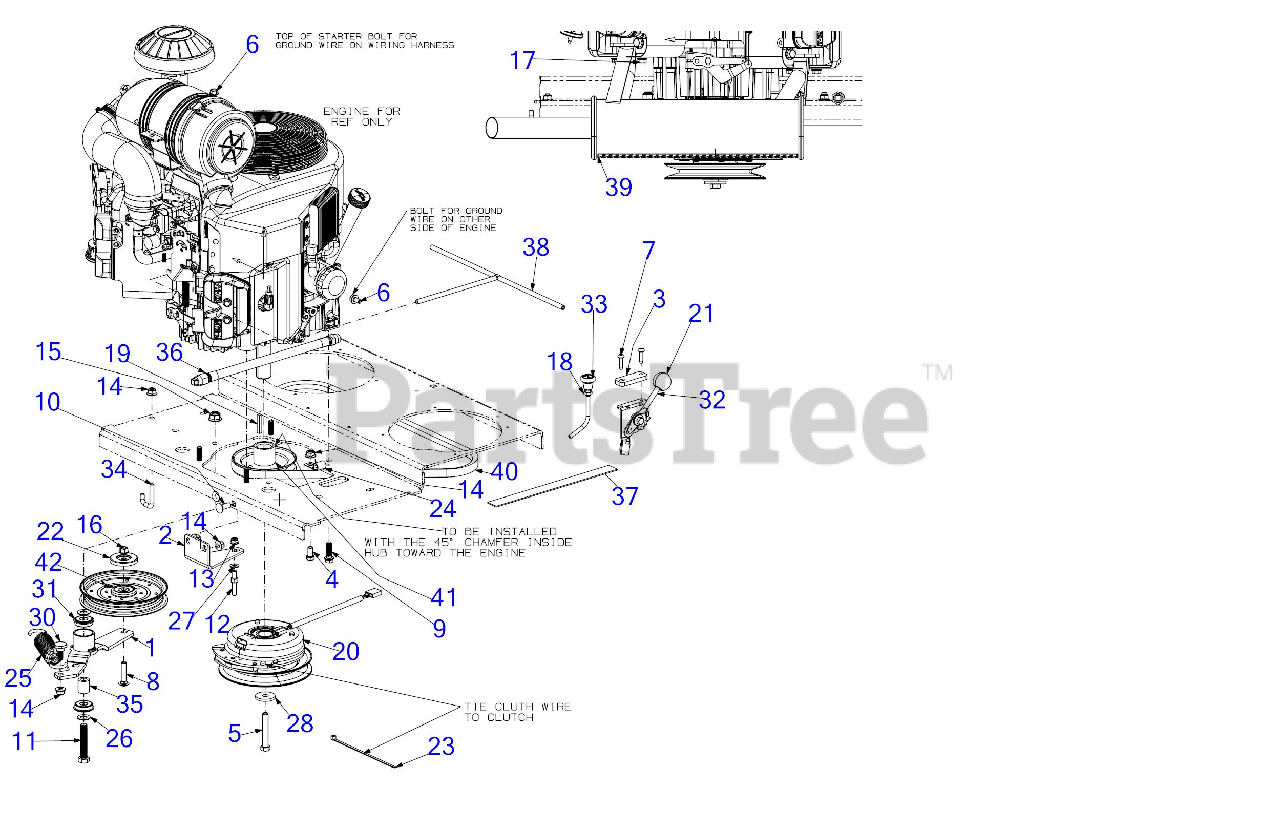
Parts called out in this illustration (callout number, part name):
1	IDLER ARM EXTENSION KIT
4	HEX SCREW 3/8-16 x .75
5	SCREW 7/16-20:2.75 GR5
6	SCREW M8 x 1.25 x 16MM GR8.8
7	SCREW 1/4-20 x 1.0
8	CARRIAGE BOLT 3/8-16 x 1.75 GR5
9	SCREW 3/8-16 x 1.25 GR5
10	CARRIAGE BOLT 3/8-16 x 1.00 GR5
11	SCREW 1/2-13 x 2.75 GR5
13	FLANGE LOCK NUT 5/16-18
16	HEX LOCK NUT
17	HEX FLANGE NUT
18	HEX JAM NUT 3/8X24
19	SQUARE KEY 1/4 x 1.50
20	ELECTRIC PTO CLUTCH
20	CLUTCH HARNESS 11.625
22	PULLEY CAP
23	7" CABLE TIE
24	J TYPE CLIP
25	EXTENSION SPRING W/HOOK
26	FLAT WASHER .510 x 1.00 x .060
27	FLAT WASHER
28	FLAT WASHER .45 x 1.5 x .172 HT
30	SHOULDER SCREW .625 x .302 x 3/8-16
31	ROLLER BEARING .5X1.37X.44
32	THROTTLE CABLE 59"
33	CHOKE CABLE
34	ROD SPRING HOOK
35	SPACER 0.51 X 0.88 X 1.00
36	OIL DRAIN HOSE
38	ROLLOVER VENT HOSE ASSEMBLY
39	KAWASAKI MUFFLER
40	TRANSMISSION BELT 61.5
41	PULLEY - PUMP DRIVE
42	IDLER PULLEY
